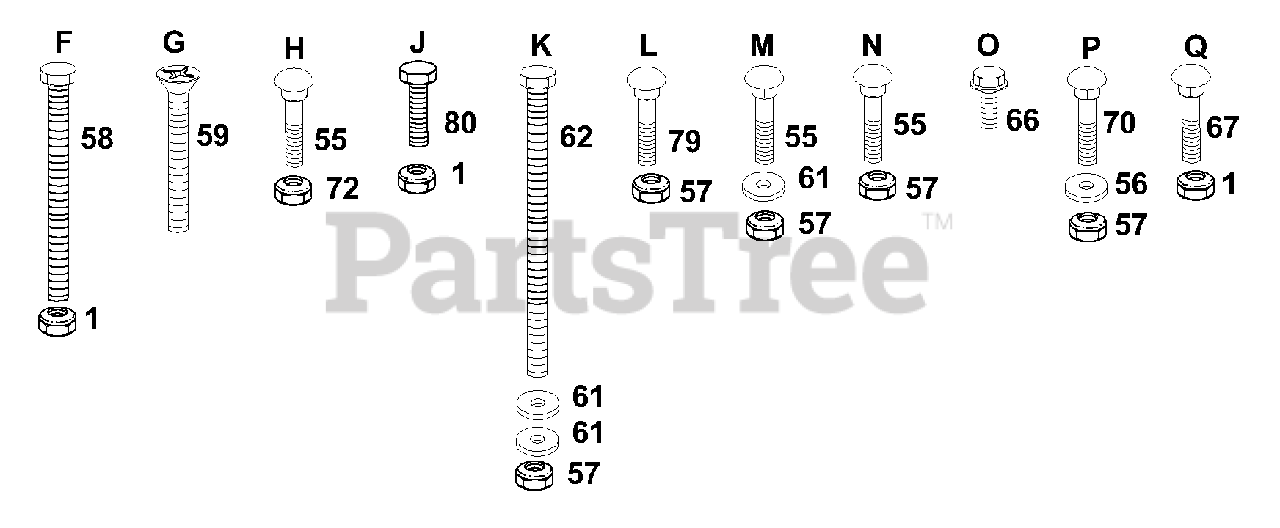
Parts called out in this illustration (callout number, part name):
1	Locknut 3/8-16
55	Bolt, Carriage 5/16-18 x 3/4
56	Washer 11/32 x 11/16 x 16 Gauge
57	Locknut 5/16-18
58	Bolt, Hex 3/8-16 x 3
59	Screw, Flat Head 3/8-16 x 2
61	Washer 11/32 x 3/4 x 16 Gauge
62	Bolt, Hex 5/16-18 x 5
66	Screw, Hex Washer Thread Rolling 3/8-16 x 3/4
67	Bolt, Carriage 3/8-16 x 3/4
70	Bolt, Carriage 5/16-18 x 3/4
72	Locknut 5/16-18
79	Bolt, Carriage 5/16-18 x 5/8
80	Bolt, Hex, Fin 3/8-16 x 1
